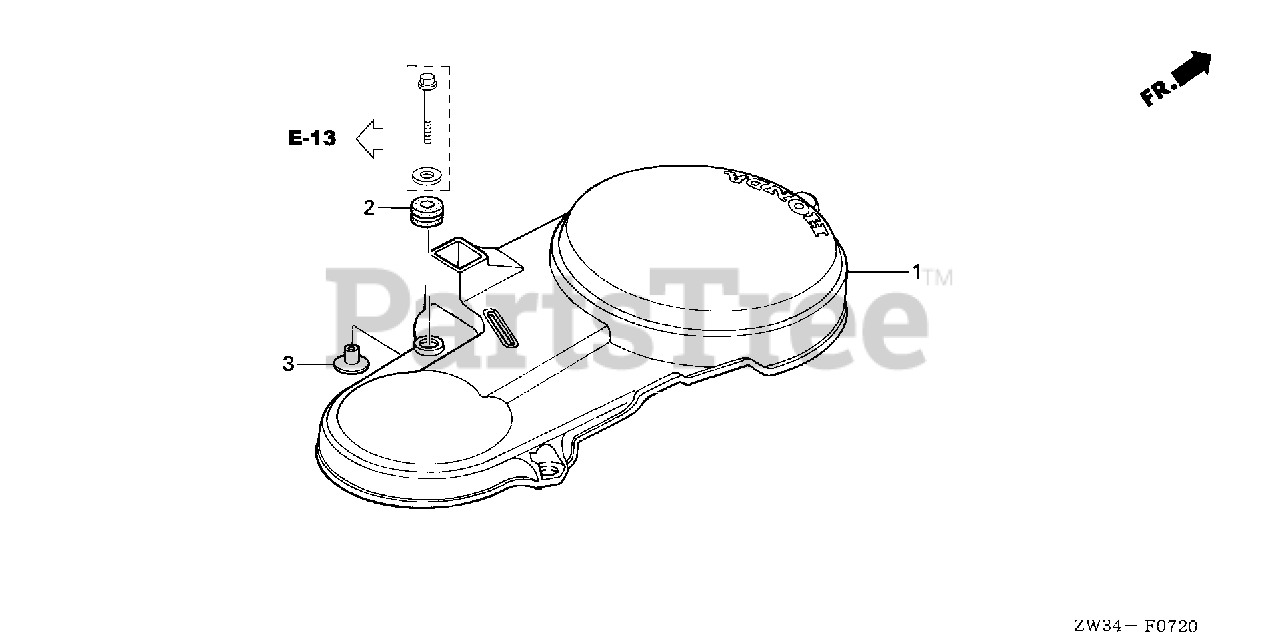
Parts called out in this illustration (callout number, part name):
1	COVER, FLYWHEEL
2	GROMMET, CASE (LOWER)
3	COLLAR, MODULE IGNITION CONTROL CASE (CDI)
